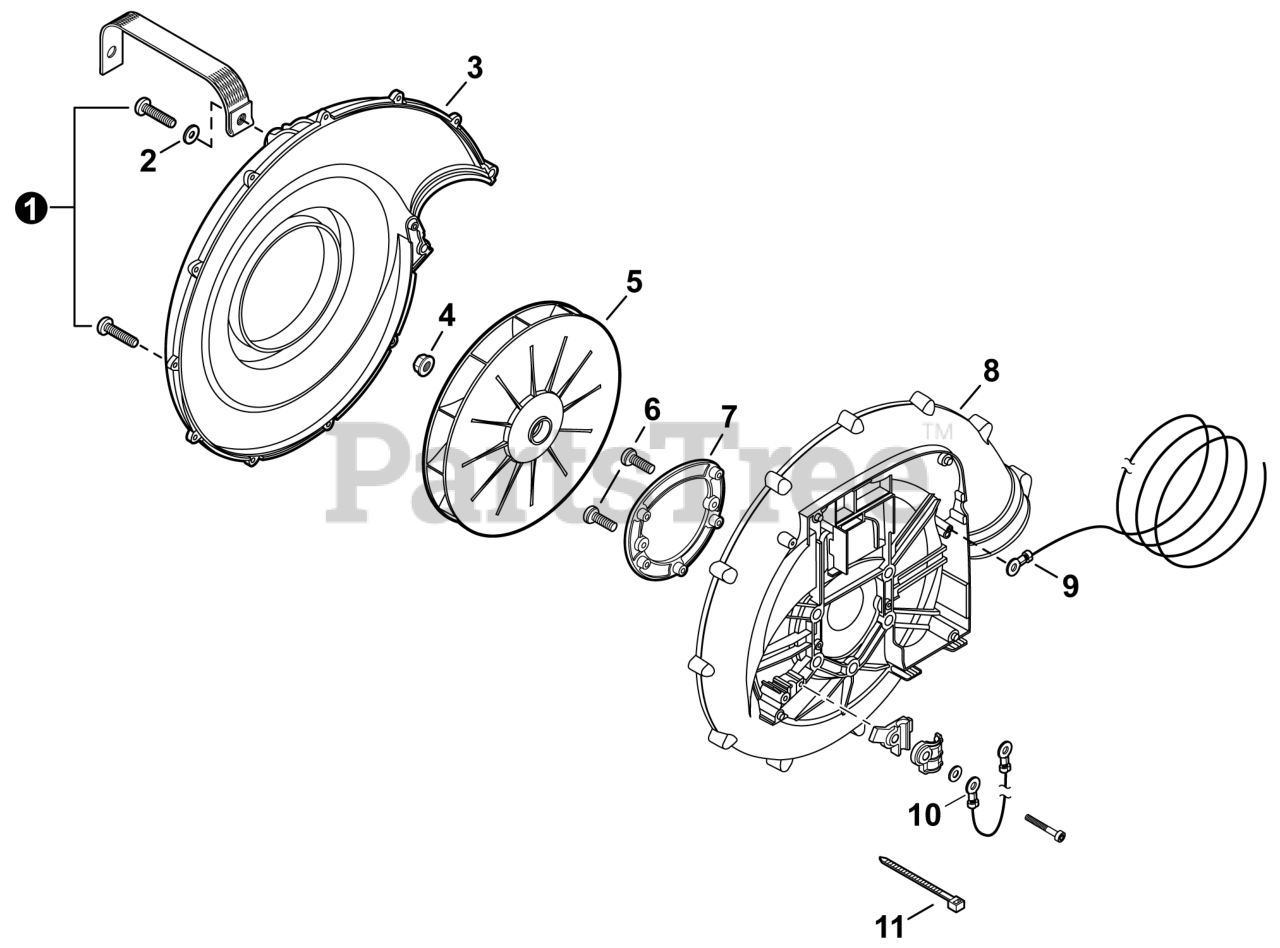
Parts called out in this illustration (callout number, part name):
1	BOLT, TORX 5×20
2	WASHER 5.5×16×2T
3	COVER, FAN
4	NUT, FLANGE 10×1.25
5	FAN, BLOWER
6	BOLT, TORX 5×16
7	PLATE, ENGINE
8	CASE, FAN
9	WIRE, STATIC DISCHARGE 890 MM
10	LEAD L= 195 MM
11	STRAP, TIE
